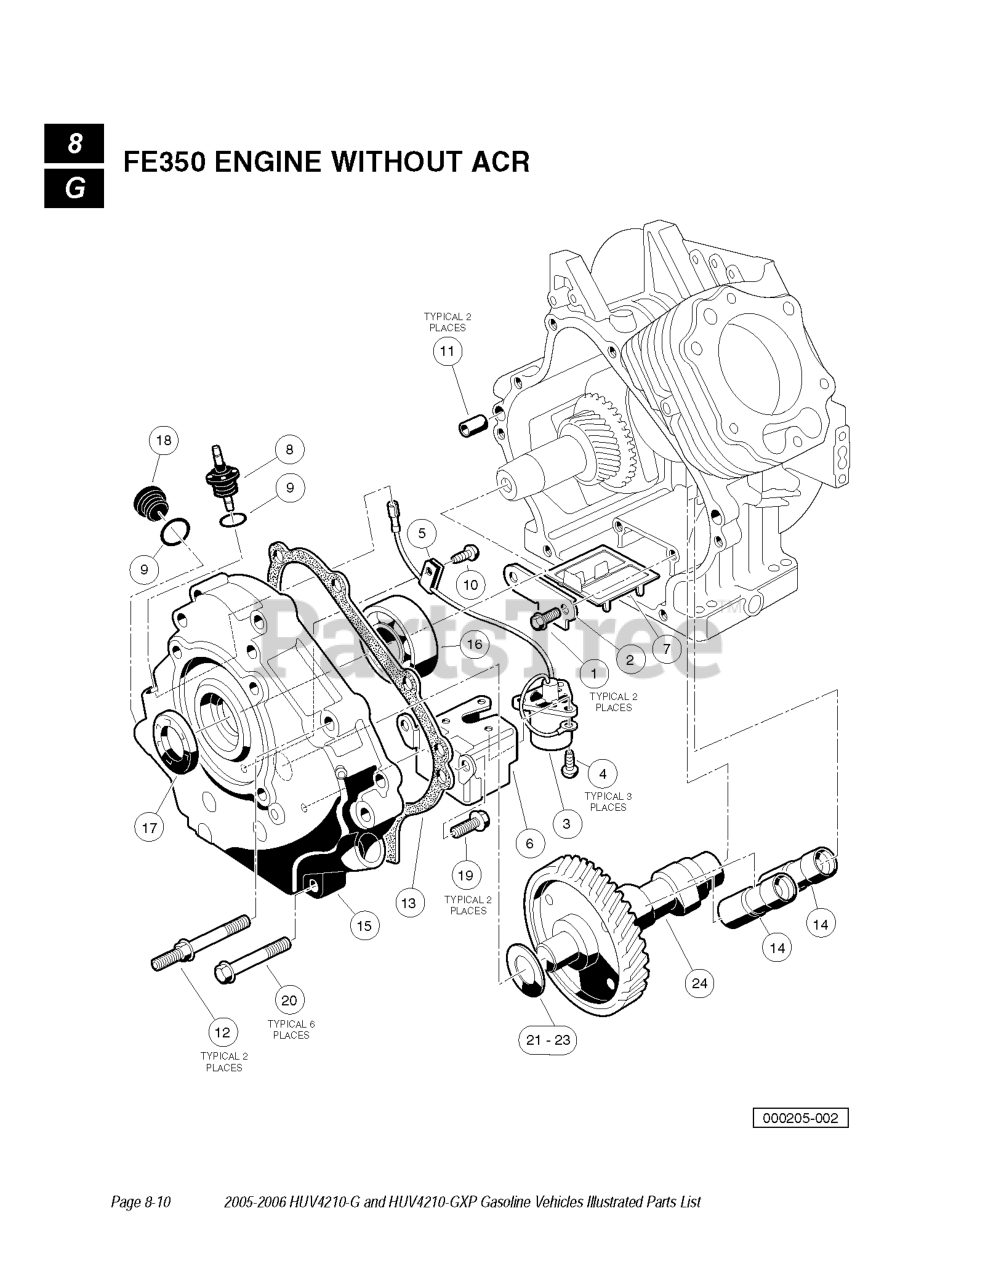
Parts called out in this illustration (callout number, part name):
1	BOLT, FLANGED
2	OIL FILTER SCREEN PLATE
3	SENSOR, FE290 OIL LEVEL
4	SCREW, PAN, CROSS
6	BRACKET, SWITCH, OIL LEVEL
7	OIL FILTER SCREEN
8	CONNECTOR - CORD
13	GASKET - CRANKCASE COVER
14	ADJUSTER, LASH
15	COVER CRANKCASE
16	BEARING, BALL
17	SEAL - OIL
20	SCREW, M8-1.25 X 45MM HEX
21	SHIM - T=0.3
22	SHIM - T=0.4
23	SHIM - T=0.5
24	CAMSHAFT, FE350 WO/ACR 44T
